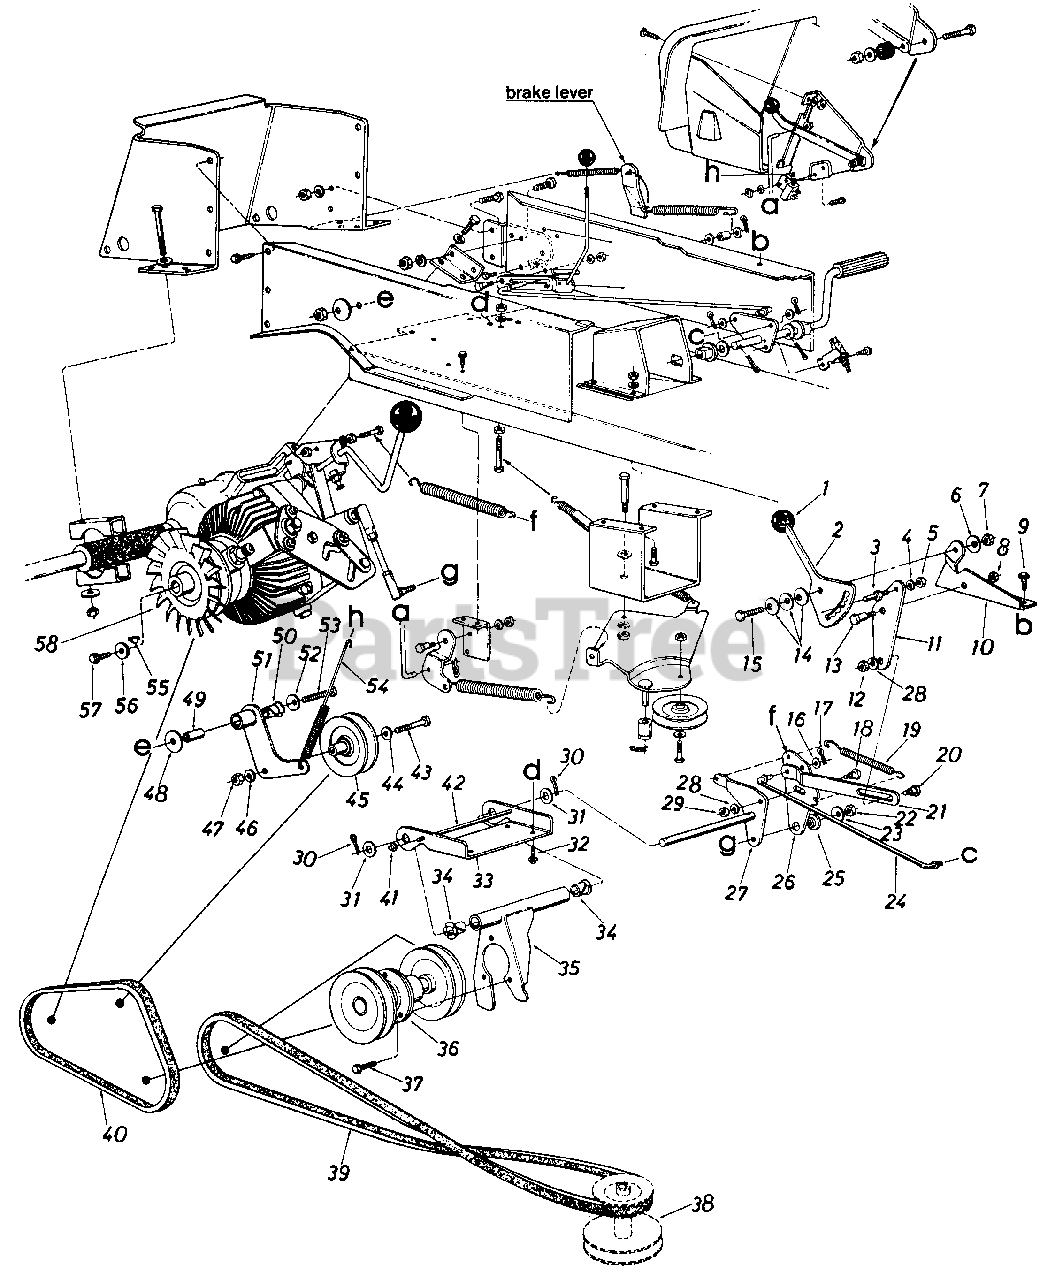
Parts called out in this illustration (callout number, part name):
1	Gear Shift Knob
2	Speed Selector Cam
3	Hex Stud .250" Dia. x .62"
4	L-Wash. 1/4" I.D.
5	Hex Nut 1/a-20 Thd.
6	Bell-Wash. .400" I.D. x 1.13" O.D.
7	Hex Ins. L-Nut 3/8-24 Thd.
8	Hex Top L-Nut 3/8-16 Thd.
9	Hex Wash. Hd. S-Tap Scr. 1/4-20 x 75" Lg.
10	Speed Selector Mtg. Brkt.
11	Speed Selector Transfer Brkt.
12	Hex Nut 5/16-18 Thd.
13	Shld. Bolt .500" Dia. x .170
14	Bell-Wash. .39" I.D. x 1.13" O.D.
15	Hex Bolt 3/8-24 x 1.00" Lg.
16	Fl-Wash. .385" I.D. x .87" O.D.
17	Cotter Pin 3/32" Dia. x .75" Lg.
18	Shld. Bolt .437" Dia. x .180
19	Extension Spring .50" Dia. x 2.75" Lg.
20	Shld. Bolt .437" Dia. x .180
21	Speed Selector Link
22	Hex Nut 3/8-24 Thd."
23	Bell-Wash .39" I.D. x 1.13" O.D.
24	Rod Speed Control .312" Dia.
25	Shld. Spacer .625" I.D.
26	Speed Cont. Transfer Swivel Brkt.
27	Speed Control Transfer Ass'y.
28	L-Wash. 5/16" I.D.*
29	Hex Nut 5/16-18 Thd.
30	Cotter Pin 1/8" Dia. x 1.00" Lg.
31	Fl-Wash. .640" kD. x 1.24" O.D.
32	Hex Wash S-Tap Scr. 1/4-20 x .50" Lg.
33	Idler Mtg. Brkt.
34	Flanged Nyliner Brg. .376 I.D. x .437
35	Mounting Brkt. Ass'y.
36	Jack Shaft Ass'y.
37	Hex Sems Bolt 5/16-18 x .75" Lg.
38	Engine P9uliey 47 5" I.D. x 5.56" O.D.
39	V-Belt 1/2" X 59.0" Lg.
40	V-Belt 1/2" X 32.0" Lg.
41	Push Cap
42	Rod 3/16" Dia. x 7.12" Lg.
43	Hex Bolt 3/8-24 x 1.50" Lg.*
44	Fl-Wash. .385" I.D. x .87" O.D.
45	Idler Pulley 4.0" O.D. x 5/8"-"V"
46	L-Wash. 3/8" I.D.*
47	Hex Nut 3/8-24 Thd.*
48	Bell-Wash. .40" I.D. x .87" O.D.
49	Spacer .38" I.D. x .62" O.D. x 1.87" Lg.
50	Flanged Nyliner Brg.
51	Idler Pivot Brkt. Ass'y.
52	Fl-Wash. .38" I.D. x .87" O.D.
53	Hex Bolt 3/8-24 x 2.00" Lg.*
54	Extension Spring .56" O.D. x 7.75" Lg.
55	#9 Hi-Pro Key .316" x .75" Dia.
56	Fl-Wash. .505" I.D. x 1.0" O.D.
57	Hex Wash. Hd. S-Tap Scr. 1/4-20 x .75" Lg.
58	Trans. Pulley & Fan Ass'y.
